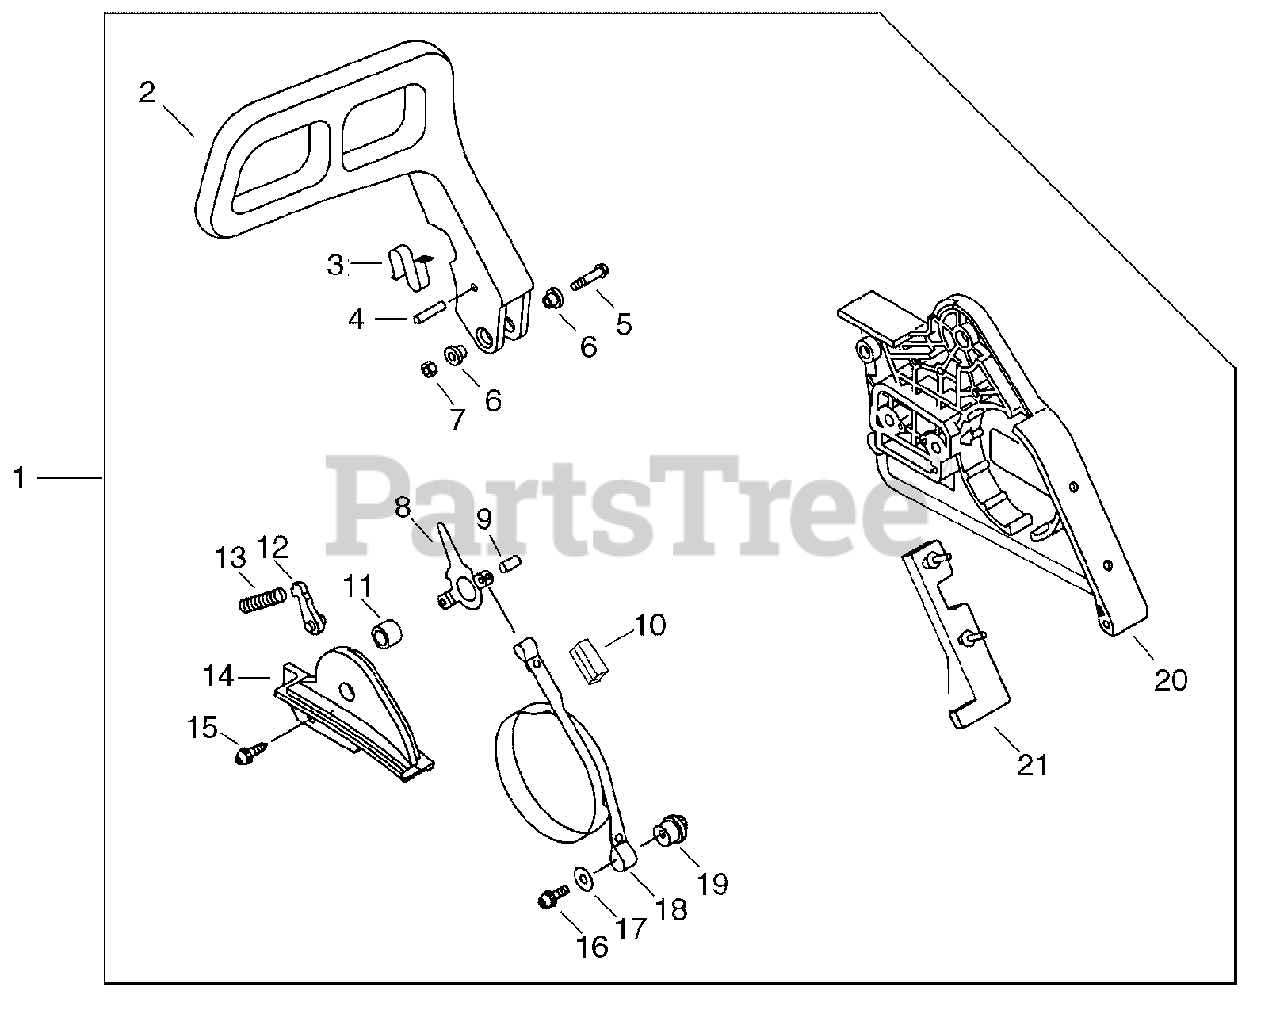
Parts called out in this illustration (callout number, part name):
1	BRAKE ASSY, CHAIN
2	LEVER, BRAKE
3	SPRING, FLAT
4	PIN 3.5×26
6	COLLAR 5.3×10×13×L5
7	NUT, LOCK M5
8	LEVER, BRAKE
9	PIN, SPRING 4×8.8
10	SEAL, BRAKE
11	WASHER 5.2×12×14
12	STOPPER, BRAKE
13	SPRING, BRAKE
14	COVER, BRAKE
15	SCREW 4×10
16	SCREW 5×25
18	BAND, BRAKE
19	ADJUSTER, BRAKE
20	GUARD, SPROCKET
